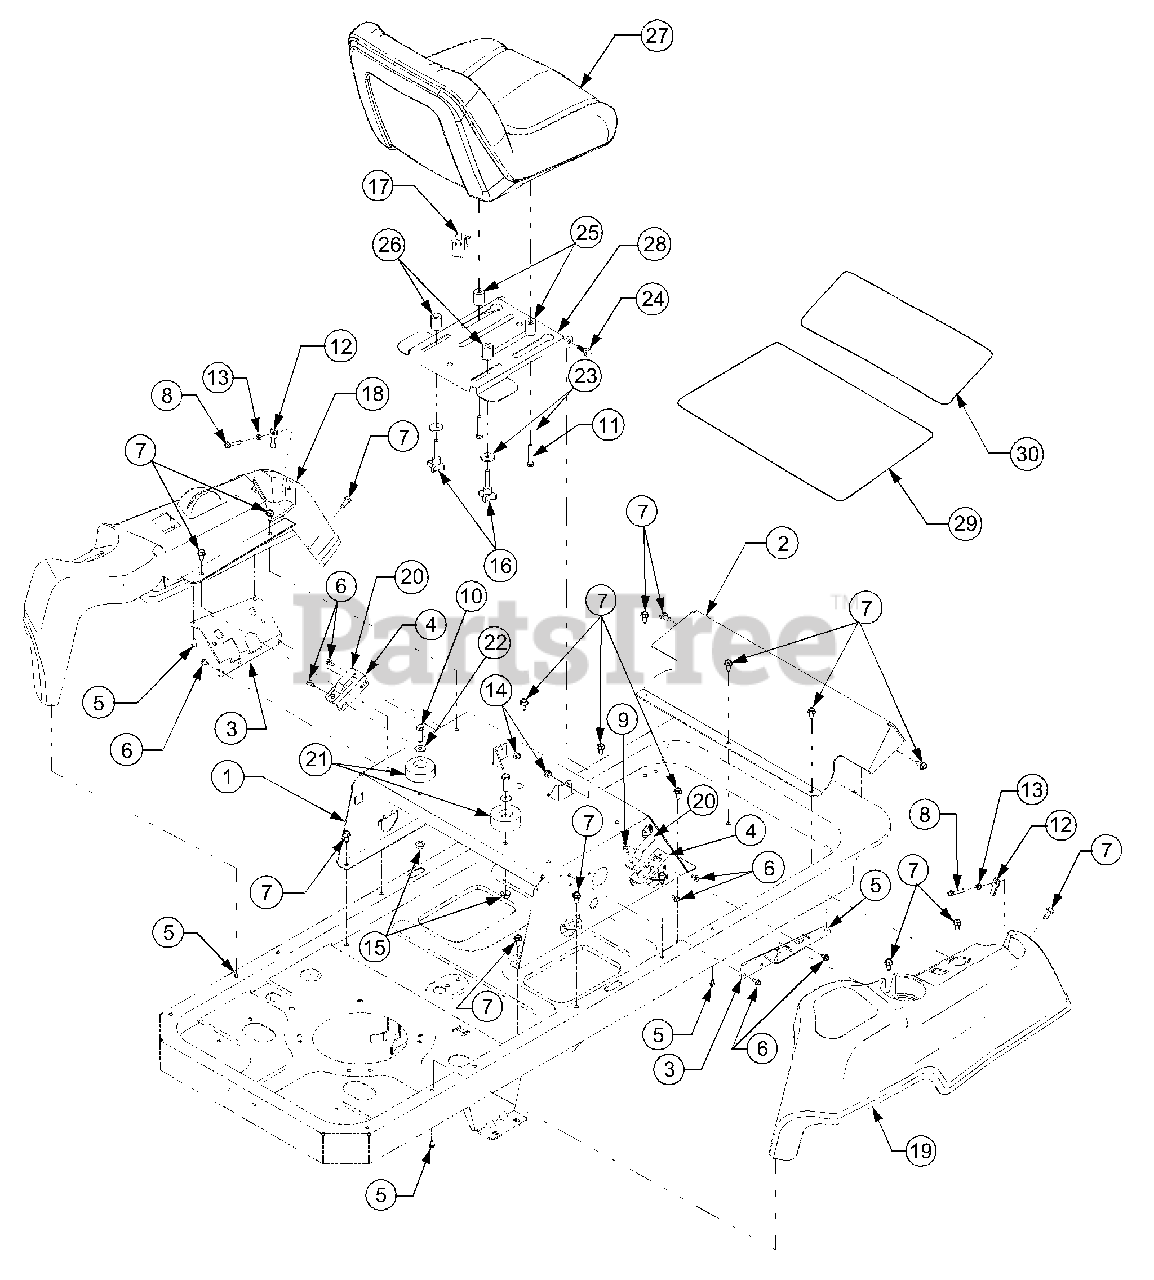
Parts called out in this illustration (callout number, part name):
5	Screw, Hex Wash. Hd Tapp #12-16 x .50
6	Screw, Hex Wash. Hd. Tapp. 1/4-20 x .5
7	Screw, Hex Wash. Hd. Tapp 5/16-18 x .625
8	Screw, Hex Wash. Hd. Tapp. 1/4-20 x 1.5
9	Screw, Hex Wash. Hd Tapp #10-16 x .375
10	Screw, Hex Cap, 3/8-16 x 1.25 GR5
11	Screw, Hex Cap, 3/8-16 x 1,75 GR5
12	Nut, U Type Speed
13	Nut, Hex Jam, 1/4-20 GR2
14	Nut, Hex Insert Lock, 5/16-18 GR5
15	Nut, Hex Flange Lock, 3/8-16 GRF
16	Knob, 5/16-18 x 1.75
17	Switch, Seat, Snap Mount, N.C.
18	Console, LH
19	Console, RH
20	Spring, Switch Actuator
22	Washer, Flat HT, .395 x .87 x .06
23	Washer, Flat HDN, .406 x 1.25 x .157
24	Screw, Shoulder, .437 x .268: 5/16-18
25	Spacer, Seat Adjustment
26	Spacer, Seat Mounting
27	Seat
29	Pad, Abrasive Foot Plate
30	Pad, Abrasive Toe Plate
777D08310	Graphic, White Outdoor
777D08311	Graphic, White Outdoor
777I22307	Graphic, Deck Height
